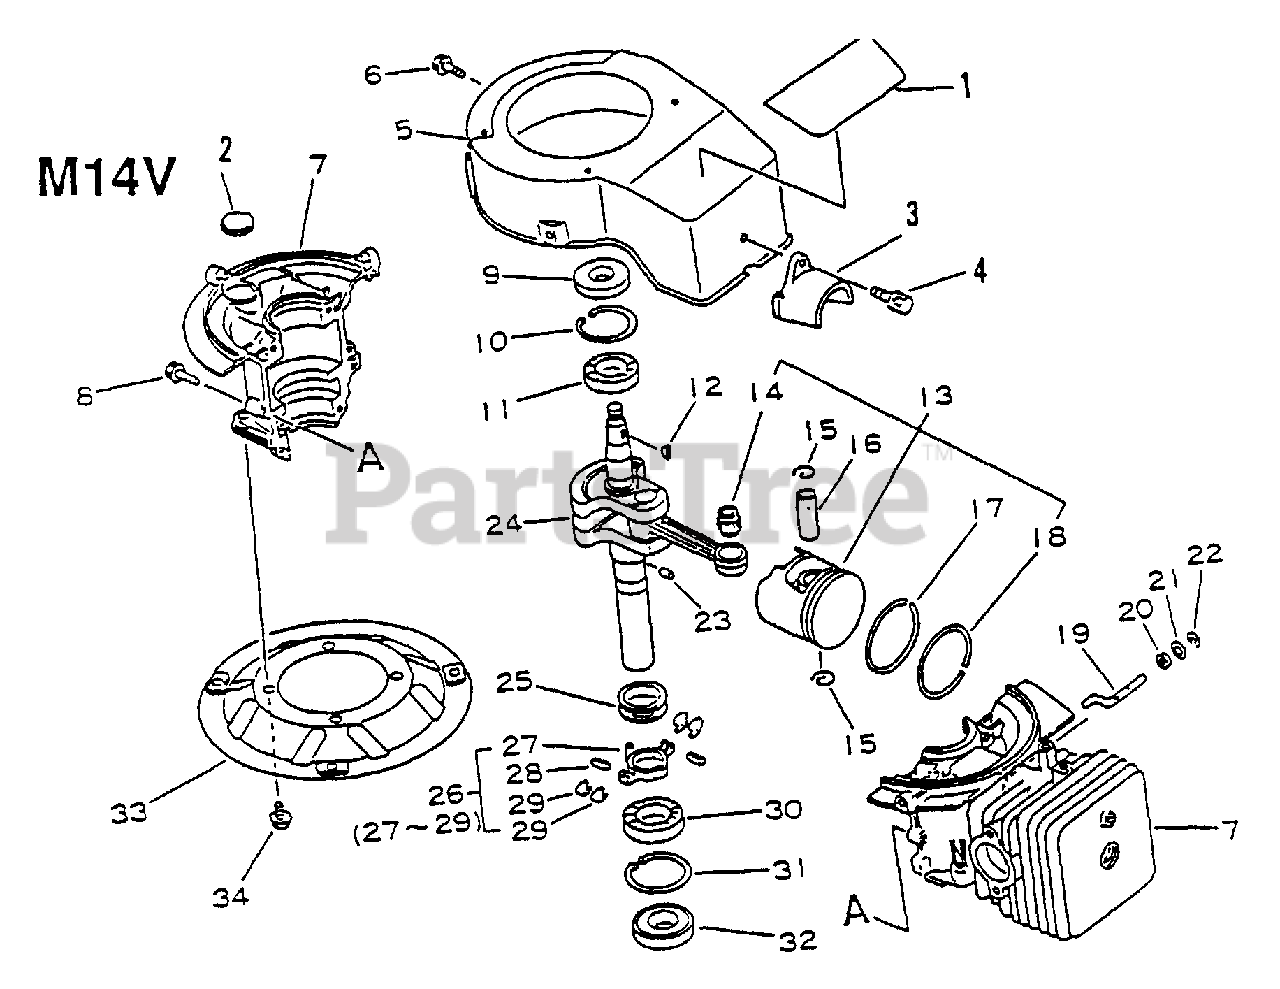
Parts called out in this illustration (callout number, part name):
1	LABEL - ECHO
2	PLUG
3	GUARD, SPARK PLUG
4	BOLT - 6×16
5	CASE, FAN
6	BOLT - 6×10
7	CRANKCASE KIT
8	BOLT - 6×25
9	SEAL, OIL
10	RING, RETAINING - 47
11	BEARING, BALL 6204/C3
13	PISTON KIT
14	BEARING, NEEDLE
15	RING, RETAINING
16	PIN, PISTON
17	RING, PISTON
18	RING, PISTON
19	SHAFT, GOVERNOR
20	SEAL, OIL
21	WASHER 5.5×18×1
22	E-RING 4
23	PIN
24	CRANKSHAFT ASSY
25	SEAL, OIL
26	WEIGHT KIT
27	HOLDER
28	PIN, SPRING 3×10
29	WEIGHT, GOVERNOR
30	BEARING, BALL
31	RING, RETAINING
32	SEAL, OIL
33	BRACKET, ENGINE
34	BOLT - 8×16
